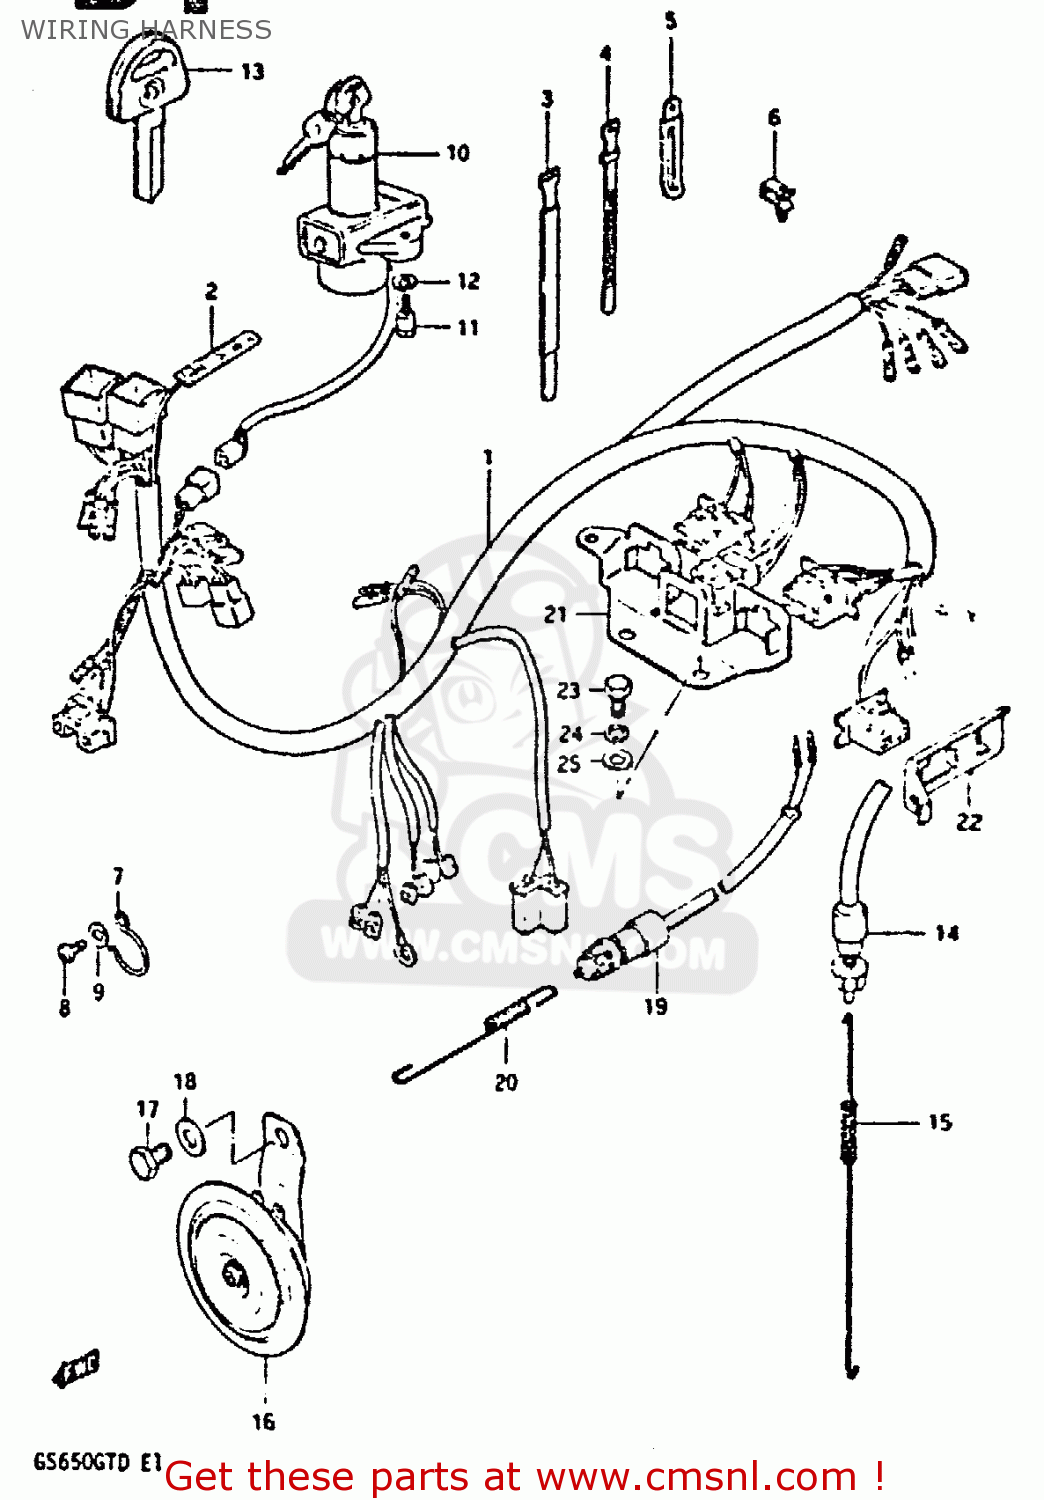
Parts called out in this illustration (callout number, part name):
1	HARNESS,WIRING
2	DIODE
3	CLAMP
4	CLAMP
5	CLAMP
6	CLIP
7	CLIP,WIRING HARNESS
8	SCREW 6X12
9	WASHER
10	LOCK ASSEMBLY,STEERING
11	BOLT
12	LOCK WASHER
13	KEY,BLANK
14	SWITCH ASSY,STOP LAMP
15	SPRING
16	HORN ASSEMBLY
17	BOLT 8X12
18	WASHER
19	SWITCH ASSEMBLY,SIDE STAND
20	SPRING
21	PLATE, COUPLER HOLDER (A)
22	PLATE, COUPLER HOLDER (B)
23	BOLT
24	LOCK WASHER
25	WASHER
